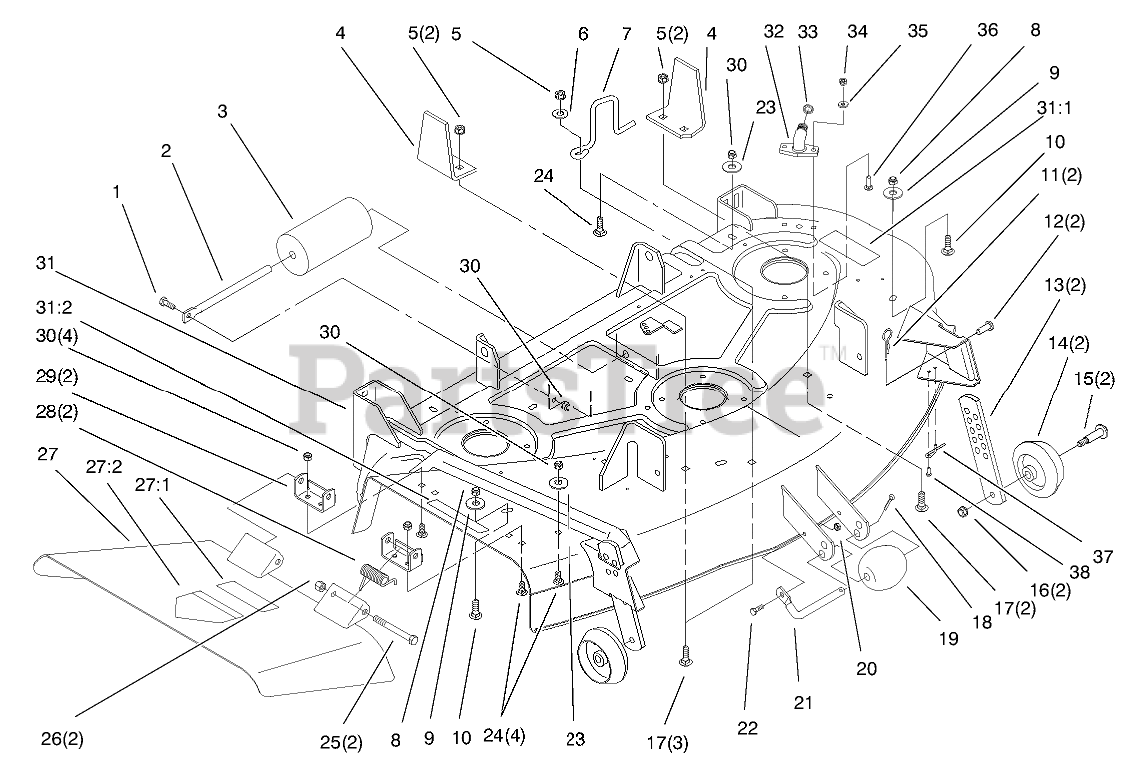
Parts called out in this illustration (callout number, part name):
1	SCREW-HH
2	ROD-ROLLER
3	ROLLER-DECK
4	Bracket Guide
5	NUT-LOCK, NI
6	WASHER
7	GUIDE-BELT
8	Nut-Lock (Only On: 78357, 78444)
9	Washer-Flat (Only On: 78357, 78444)
10	Bolt-CARR (Only On: 78357, 78444)
11	PIN-HAIR
12	PIN-CLEVIS
13	PLATE-GAGE, WHEEL
14	WHEEL-GAGE
15	SCREW-SHOULDER, HWH
16	NUT-LOCK, NI
17	BOLT-CARR
18	PIN-COTTER
19	ROLLER
20	NUT-LOCK, NI
21	SHAFT-ROLLER
22	SCREW-HH
23	Washer-Flat (Only On: 78357, 78444)
24	Bolt-CARR (Only On: 78357, 78444)
25	SCREW-HH
26	NUT-HEX
27	Deflector ASM (Only On: 78357, 78358)
27	Deflector ASM (Only On: 78444)
27:1	Decal-Danger (Only On: 78357, 78358)
27:1	Decal-Danger (Only On: 78444)
27:2	Decal-Danger (Only On: 78444)
27:2	Decal-Danger (Only On: 78357, 78358)
28	SPRING
29	BRACKET-PIVOT
30	Nut-Lock (Only On: 78357, 78444)
31	Deck ASM (Only On: 78357, 78358)
31	Deck ASM (Only On: 78444)
31:1	Decal-Danger (Only On: 78357, 78358)
31:1	Decal-Deflector Danger (Only On: 78444)
31:2	Decal-Danger (Only On: 78357, 78358)
31:2	Decal-Danger (Only On: 78444)
32	Nut-Lock (Only On: 78444)
33	Washer-Flat (Only On: 78444)
34	Fitting-Washout (Only On: 78444)
35	0-Ring (Only On: 78444)
36	Bolt-CARR (Only On: 78444)
37	SPRING-GAGE, WHEEL
38	SCREW-HWHTF
